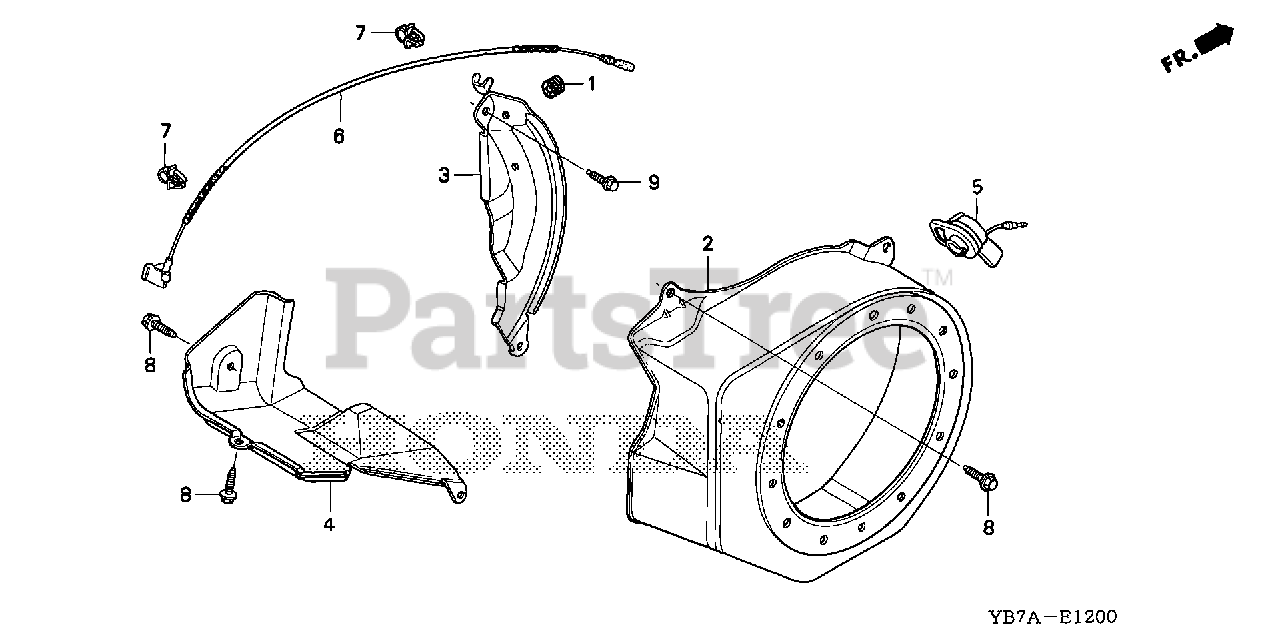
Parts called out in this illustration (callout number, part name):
2	COVER, FAN *R280* (POWER RED)
3	PLATE, SIDE (STD)
5	SWITCH ASSY., ENGINE STOP
5	SWITCH ASSY., ENGINE STOP (TOYO DENSO)
6	WIRE, STOP SWITCH (370MM)
8	BOLT, FLANGE (6X12) (CT200)
9	BOLT, FLANGE (6X20) (CT200)
